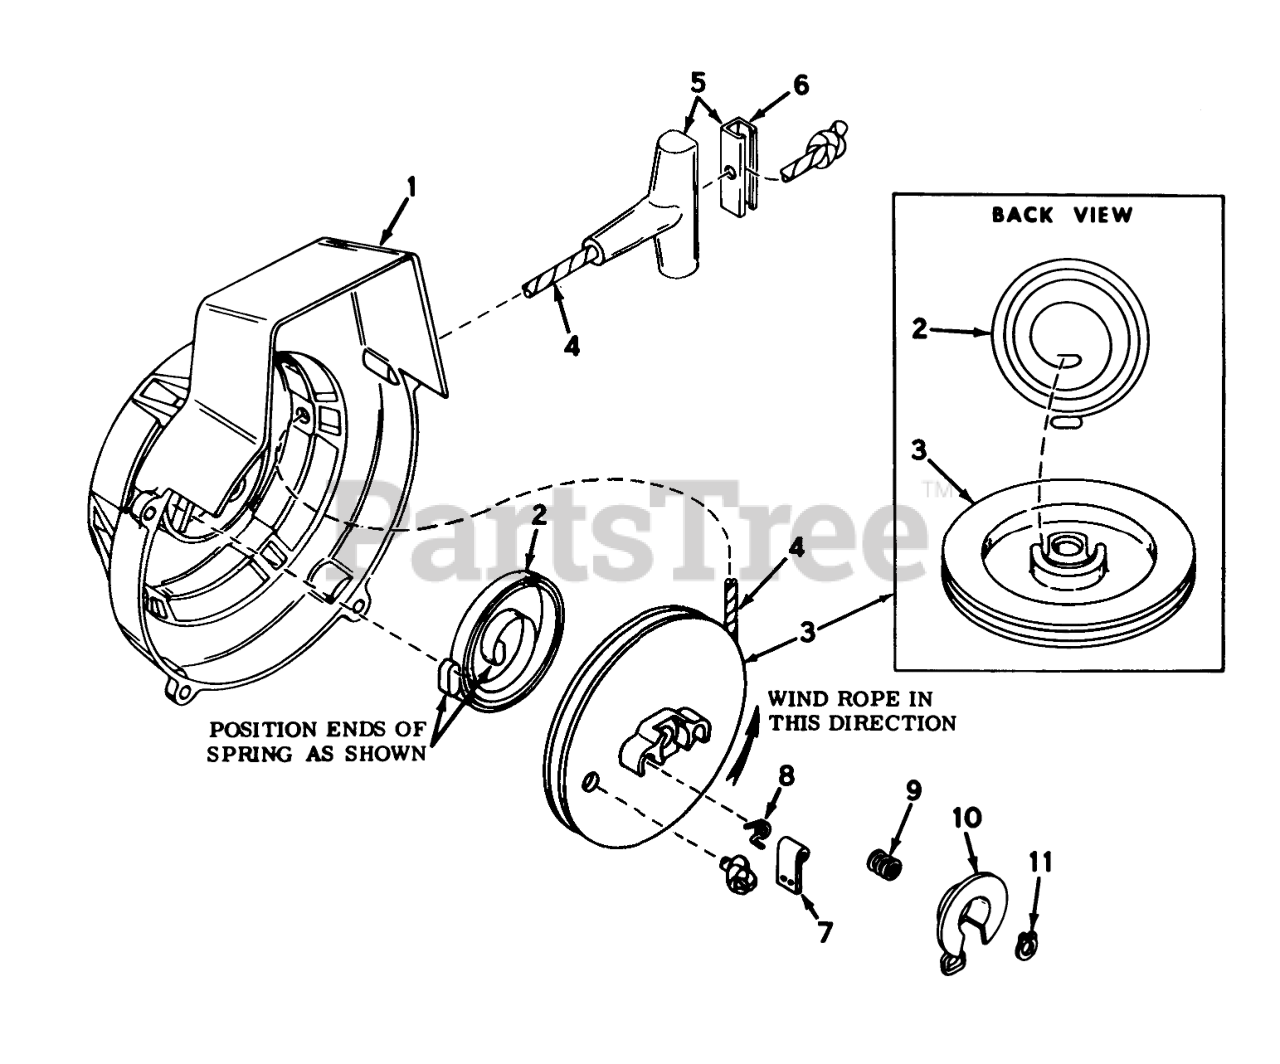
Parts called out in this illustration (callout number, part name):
1	Housing Assy., Shroud & Starter
2	Spring, Rewind
3	Pulley, Starter rope (Incl. #8)
4	Rope-Starter
5	Handle Assembly, Starter Rope (Incl. #6)
6	Insert, Handle
7	Dog, Starter
8	Retum Spring, Left Hand Wound
9	Spring, Brake
11	"E" Ring Truarc
